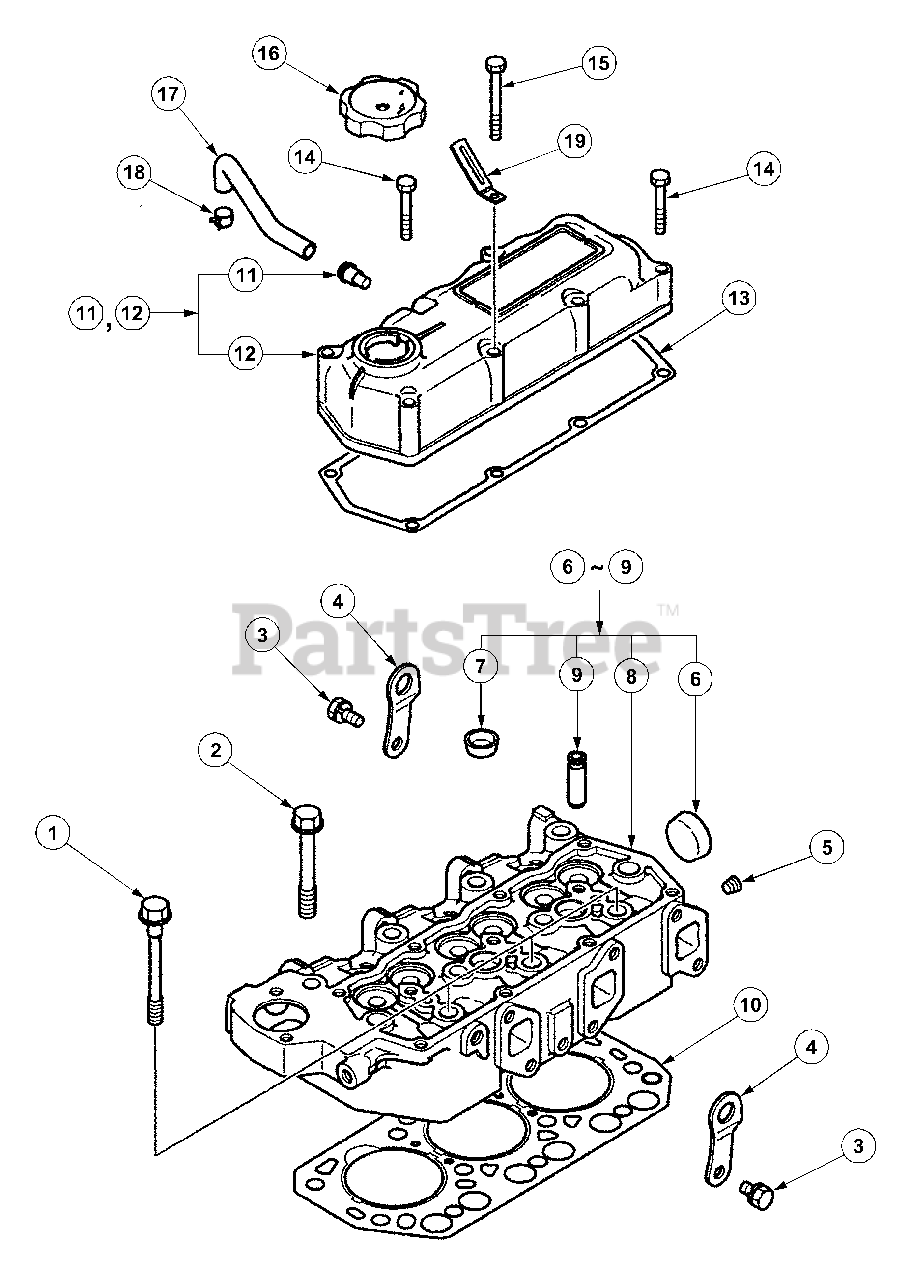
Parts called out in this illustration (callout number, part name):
1	Bolt,Cyl Head
2	Bolt,Cyl Head
4	Hanger,Engine
6	Cap,Sealing
7	Cap,Sealing
8	Cylinder Head
10	Gasket,Cyl Head
11	Pipe
12	Cover,Rocker
13	Gasket,Rocker
16	Cap,Oil Filter
17	Hose,Air Breather
